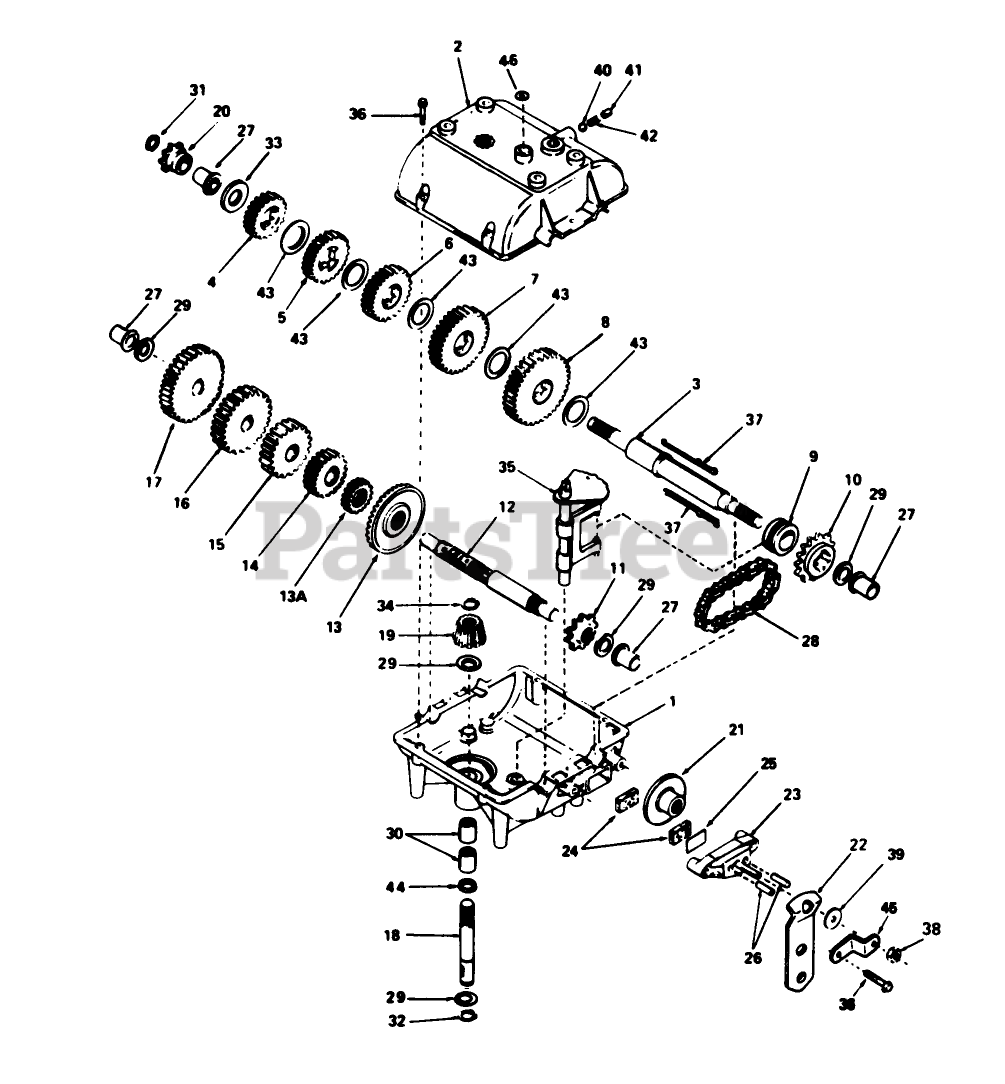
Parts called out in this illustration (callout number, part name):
1	Case-Transmission
2	Cover-Transmission
3	Shaft-Output
4	Gear-Spur 20 teeth
5	Gear-Spur (22 teeth)
6	Gear-Spur, 25 Teeth
7	Gear-Spur, 30 Teeth
8	Gear-Spur, 35 Teeth
9	Collar-Shift
10	Sprocket-18 Teeth
11	Sprocket-9 Teeth
12	Countershaft
13	Gear-Bevel (42 Teeth)
13A	Gear-Spur 15 Teeth
14	Gear-Spur, 20 Teeth
15	Gear-Spur, 25 Teeth
16	Gear-Spur (28 teeth)
17	Gear-Spur (30 teeth)
18	Shaft-Input
19	Bevel Pinion-Input
20	Sprocket (8Teeth)
22	Lever-Brake
23	Nozzle-Carburetor
24	Brake Pad
25	Brake Pad Plate
26	Dowel Pin
27	Bushing-Flange
28	Chain-Roller #41
29	Washer
30	Bearing-Needle
31	Piston Asm (.020 O S)
32	Ring-Snap
33	Washer
34	Ring-Retainer
35	Rod and Fork ASM
36	Ring Set (.020 O S)
38	Locknut
39	Washer
40	Ball-Steel
41	Screw-Set
42	Spring
43	Washer
44	O Ring
45	Bracket
46	Cut Seal-Square
